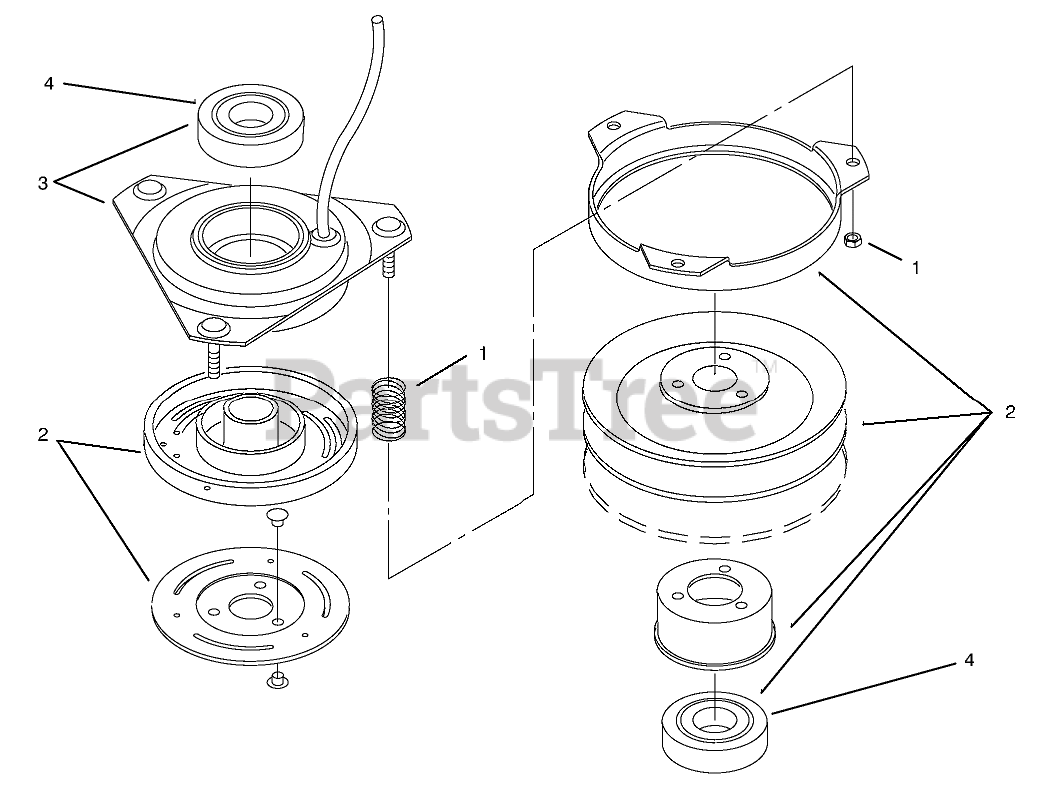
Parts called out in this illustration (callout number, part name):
1	ACCESSORY PKG SRVC PART
2	Rotor & Armature Asm (Only On: 70264)
2	Rotor & Armature ASM (Only On: 70246)
3	FIELD ASSY (SRVC PART)
4	BEARING-ELEC CLUTCH
